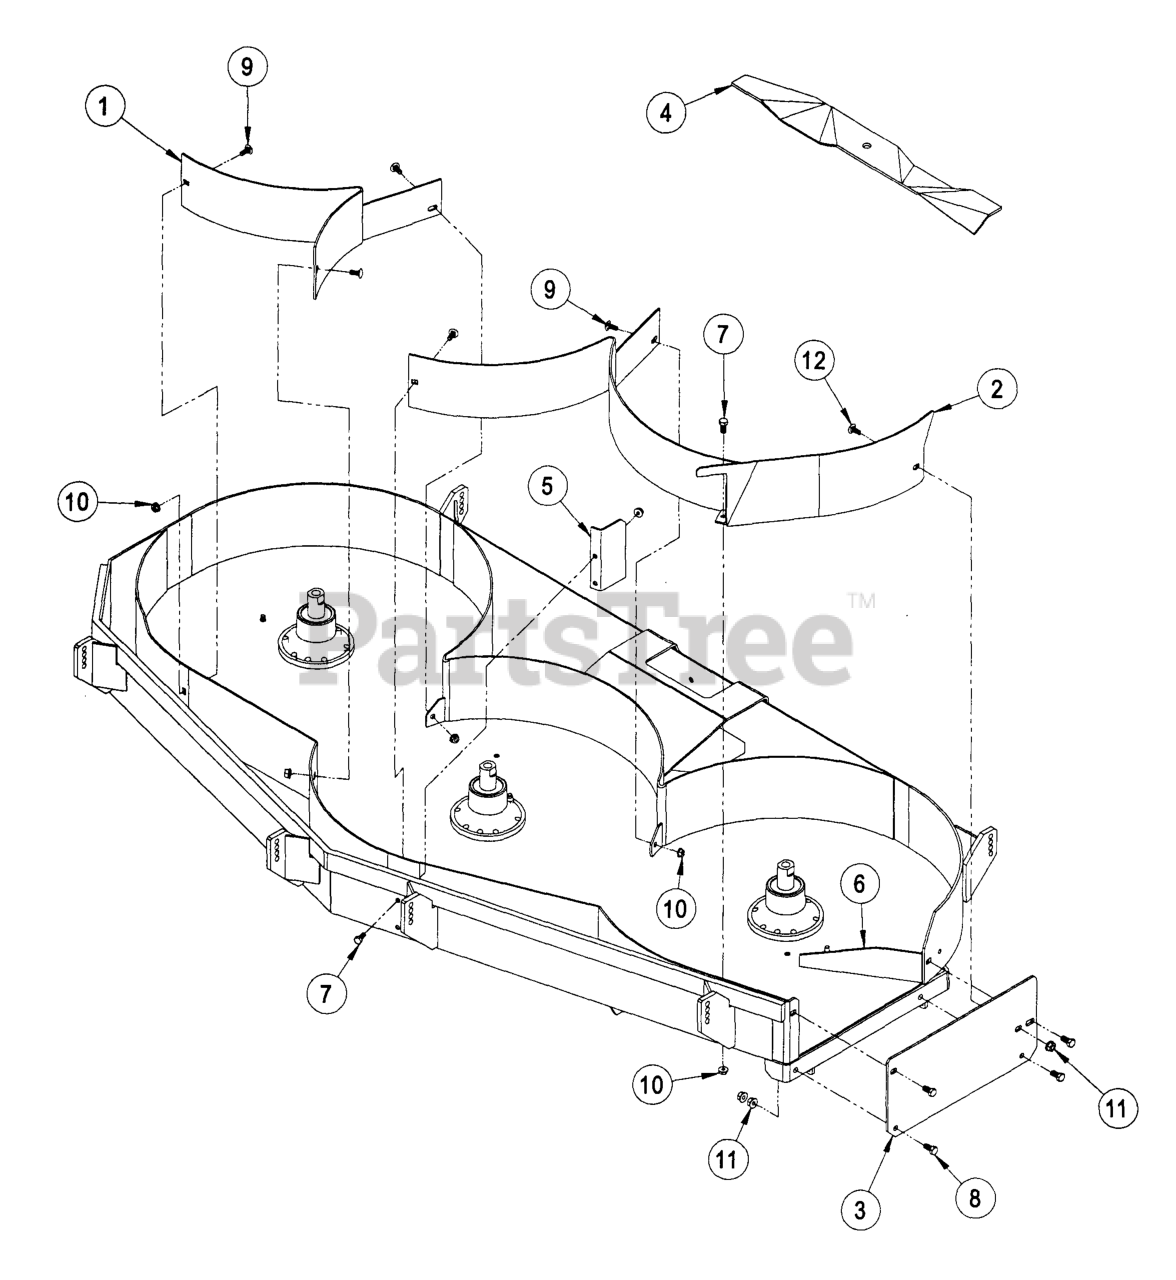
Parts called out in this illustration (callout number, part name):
1	Baffle Weldment - Lh Mk724
2	Baffle Weldment - Rh Mk724
3	PLATE-MULCH COVER, 724
6	WLD,BAFFLE DISCHARGE
